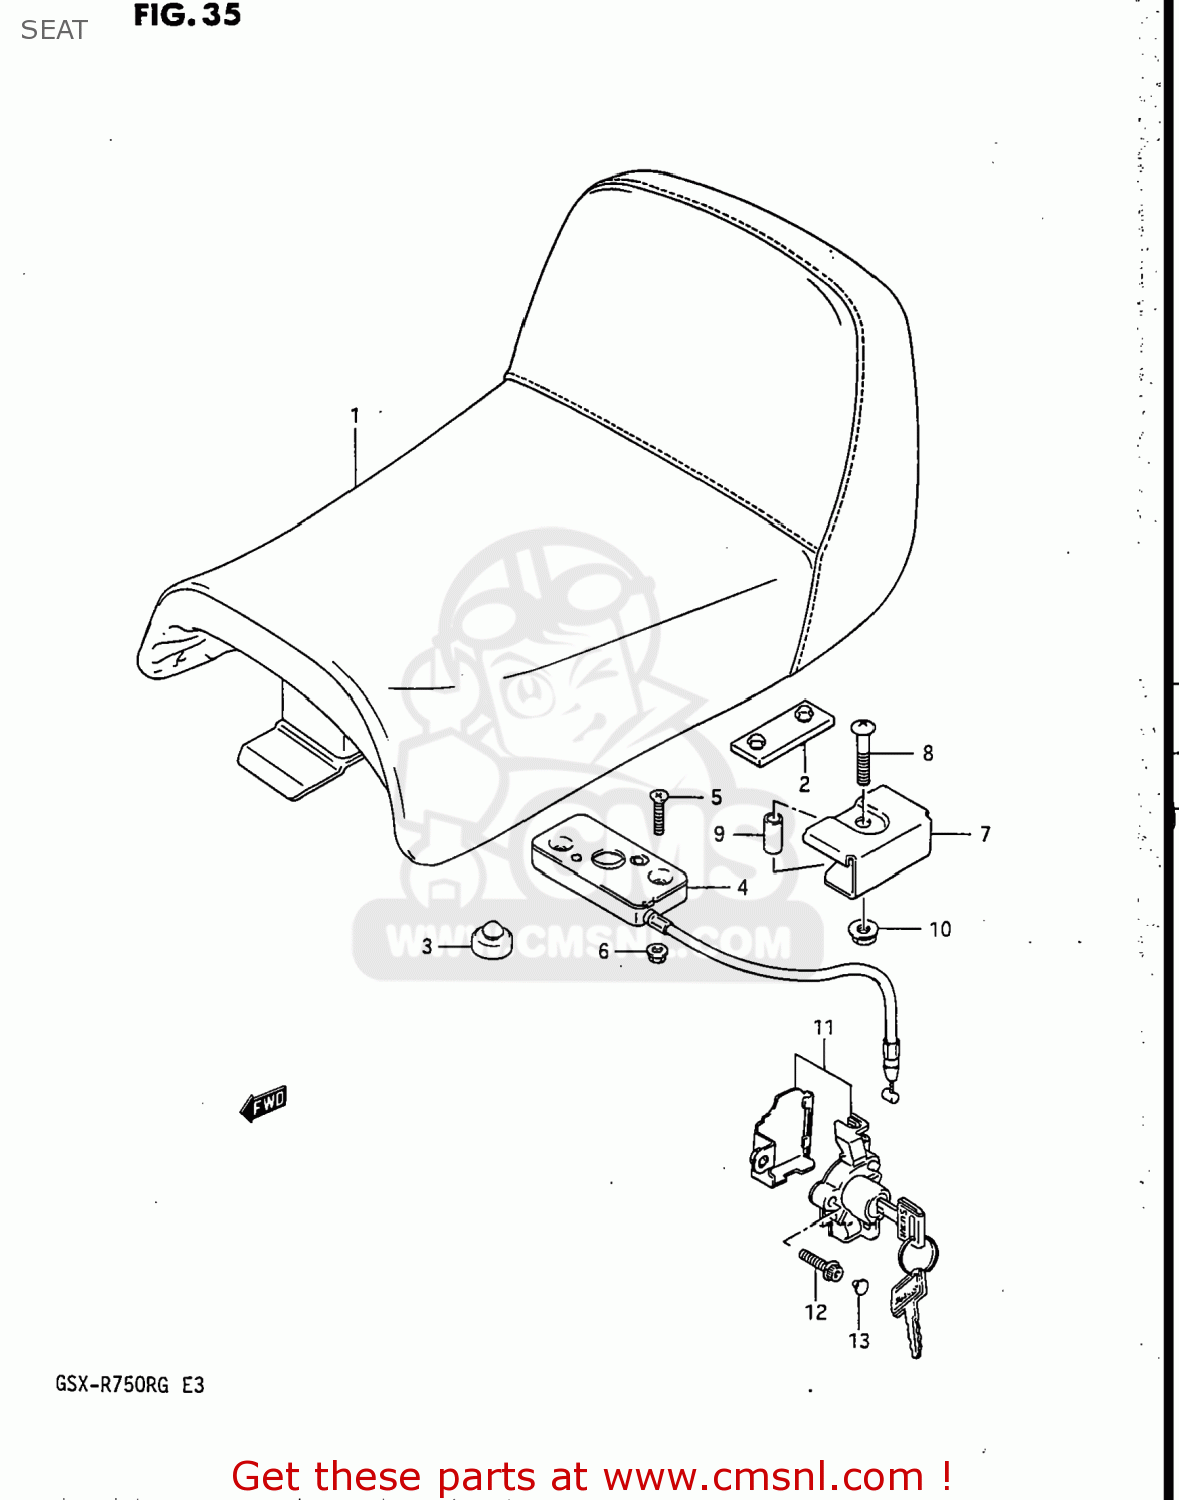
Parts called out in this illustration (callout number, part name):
1	SEAT ASSEMBLY
2	CUSHION(11.5X22X20)
3	CUSHION
4	BRACKET,SEAT SUPPORT,R
5	SCREW
6	NUT
7	PLATE,SEAT CUSHION
8	SCREW
9	SPACER (6.4X9X17.5)
10	NUT
11	LOCK SET
12	PLUG ,6X20
13	CAP(OD:10)
